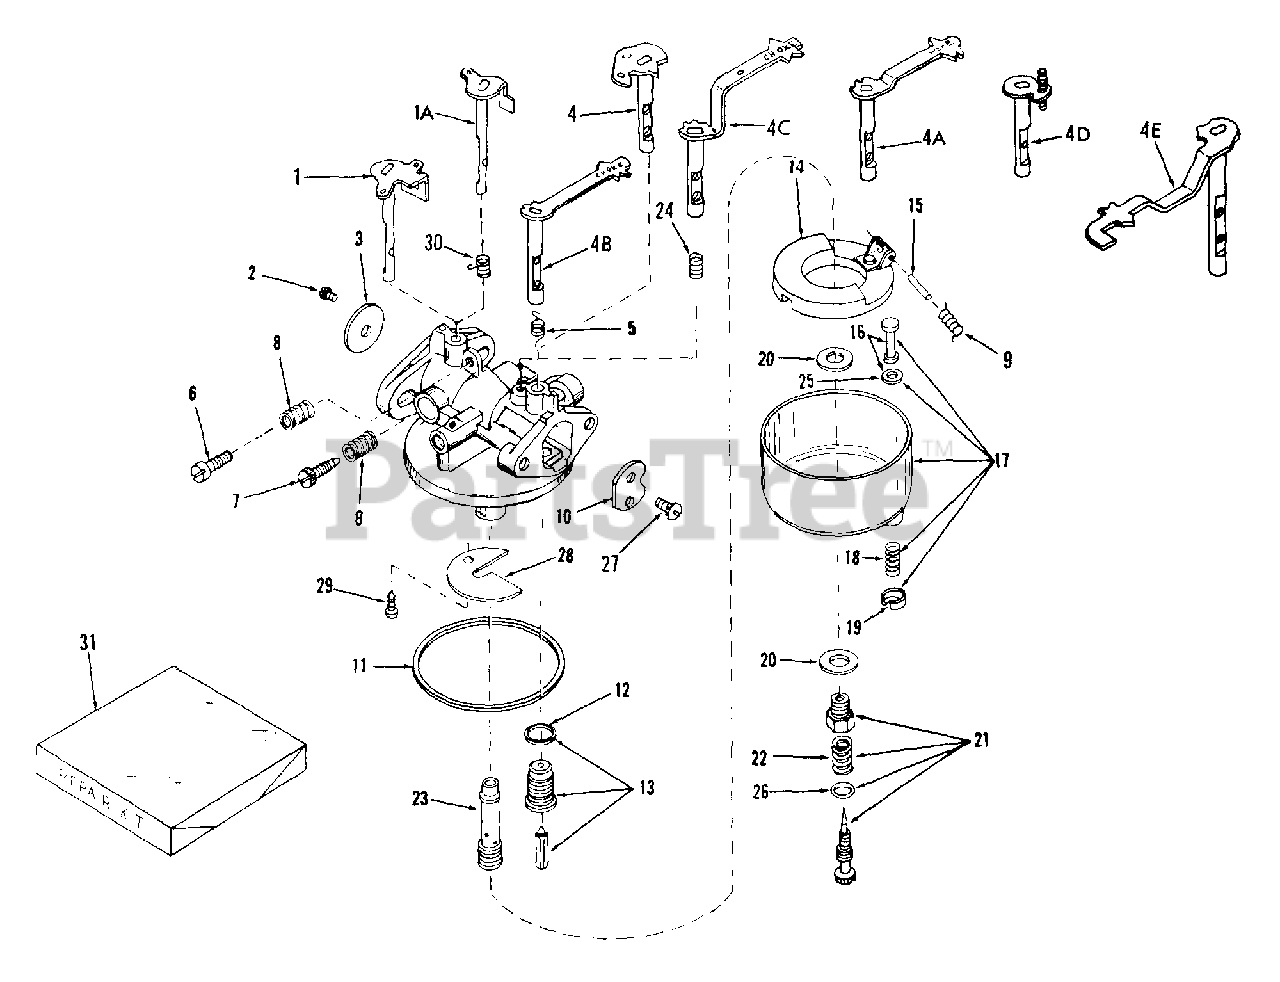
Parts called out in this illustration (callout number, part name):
1	"Shaft & Lever Assy., Throttle
2	Screw, Sems, 6-32 x 3/16
3	Shutter, Throttle
4	Shaft & Lever Assy., Choke
5	Spring, Choke return
6	Screw, Throttle adjusting
7	Needle, Idle adjusting
8	Spring, Adjusting needle
10	Shutter, Choke
11	Gasket, Bowl-to-body
12	Gasket, Valve seat
13	Valve, Seat & Gasket Assy.
15	Shaft, Float
16	Stem Assy., Bowl drain
17	Bowl & Drain Assy.,
18	Spring, Bowl drain
19	Retainer Bowl grain stem
20	Gasket, bowl-to-body
21	Needle Assy., Power adjusting
22	Spring, Power needle
23	Nozzle, Main
25	Gasket, Drain stem
26	"O" Ring
27	Screw, Sems
28	Baffle, Carburetor
29	Screw, Baffle
30	Spring, Throttle return
31	Repair Kit
